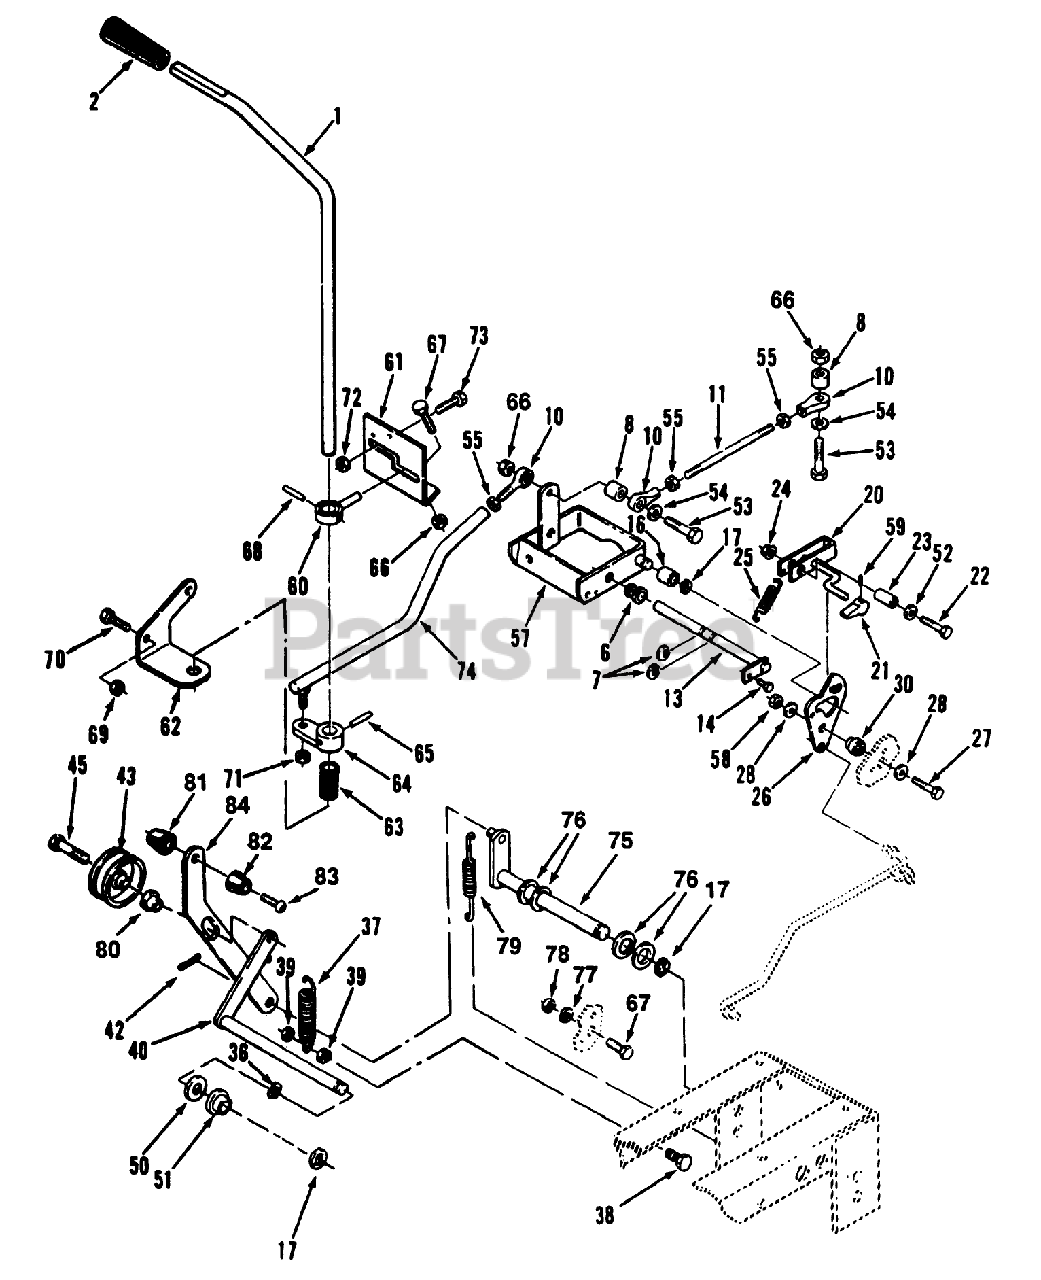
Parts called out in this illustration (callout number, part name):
1	ROD-MOTION CONTROL
6	BUSHING-NYLINER
8	BEARING CAM ROLLER
10	ROD END, 1/4-28
11	ROD-CONTROL
14	SCREW
16	BEARING-CAM RETURN
21	KNOB-PARKING BRAKE
22	SCREW-HH
23	SPACER
27	SCREW-HH
28	WASHER-FLAT
36	WASHER-WAVE
37	SPRING-EXTENSION
38	SCREW-HH
42	Pin-Cotter
43	PULLEY-IDLER
45	BOLT-SPECIAL HEX
50	WASHER-FLAT
51	BUSHING-FLANGED
52	WASHER-FLAT
54	WASHER-FLAT
55	NUT-JAM
58	NUT-LOCK, NI
59	PIN-SPIROL 3/32X5/8
60	GUIDE-CONTROL
63	SPRING-COMPRESSION
65	Pin-Spirol
66	NUT-LOCK, NI
67	SCREW-HH
68	SPIROL PIN 7/32X7/8
69	NUT-LOCK, NI
70	SCREW-HH
71	NUT-LOCK
72	NUT-LOCK, NI
73	SCREW-HH
74	ASSY-ROD & BALL JOINT
76	WASHER-FLAT
77	WASHER-LOCK/EXT
78	NUT-JAM
79	SPRING-EXTENSION
80	SPACER-BRAKE LINK
81	KNOB
82	KNOB
83	BOLT-4
